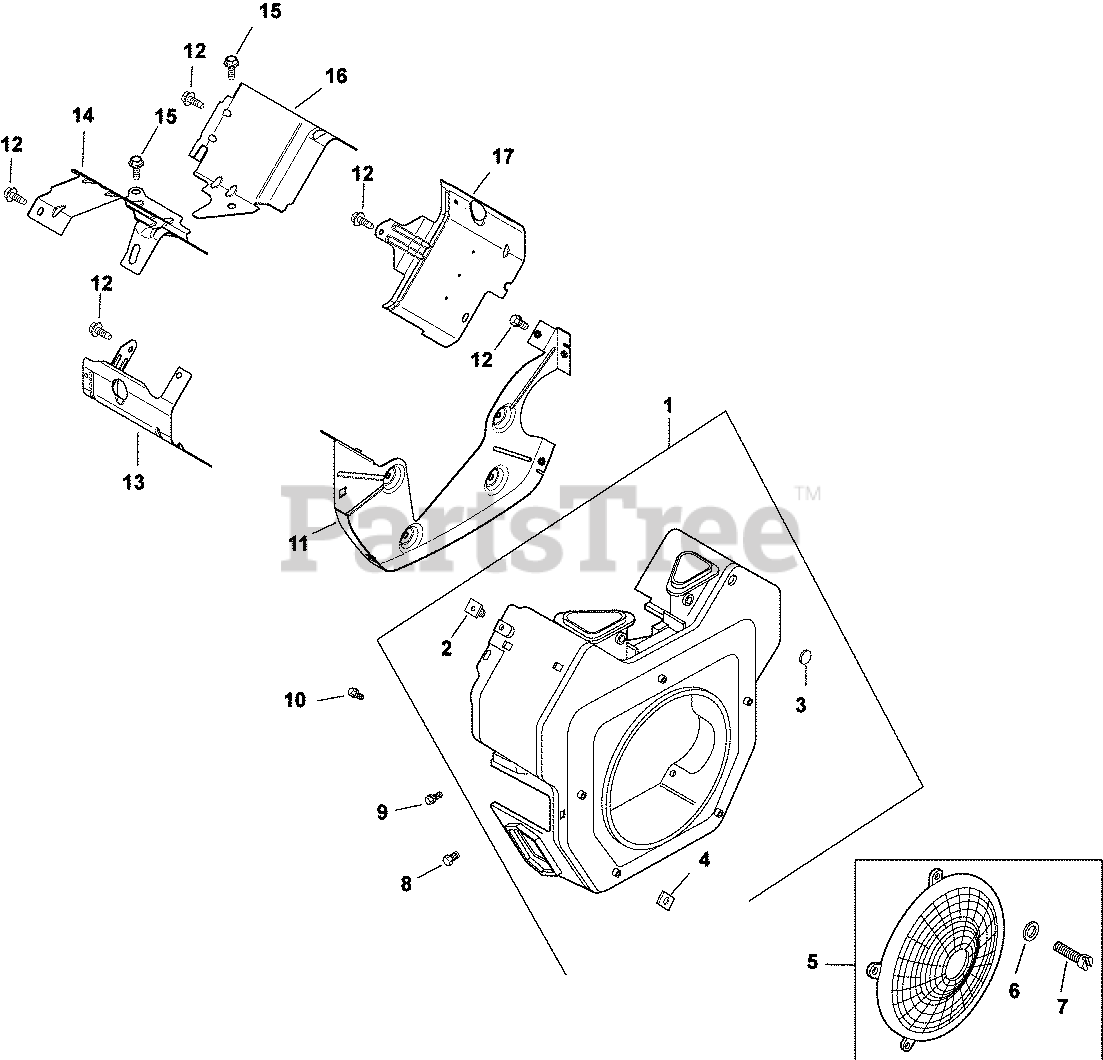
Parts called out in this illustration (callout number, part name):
1	KIT, BLOWER HOUSING ASSEMBLY USE 24 027 479-S
2	NUT, PLASTIC
3	PLUG, BUTTON 9/16
4	NUT, PLASTIC (KM)-USE 25 100 37-S
5	KIT, FIXED GUARD
6	WASHER, FLAT 7/32"
7	SCREW, LBD SCKT PAN M5X0.8X10
8	SCREW,FLG THD FRM M6X1.0X16-(#25086397S)
9	SCREW - USE M-545016-S
10	SCREW,FLG THD FRM M5X0.8X16-(#25086398S)
11	PLATE, BACKING-USE 24 146 59-S
12	SCREW, FLG THD FRM M5X.8X20-(#25086399S)
13	BAFFLE, VALLEY #2 SIDE-USE 24 063 94-S
14	BAFFLE, VALLEY (CH)-USE 24 063 93-S
15	SCREW, FLG THD FRM M5X.8X10
16	BAFFLE, RIGHT BARREL-USE 24 063 85-S
17	BAFFLE, LEFT BARREL -USE 24 063 88-S
